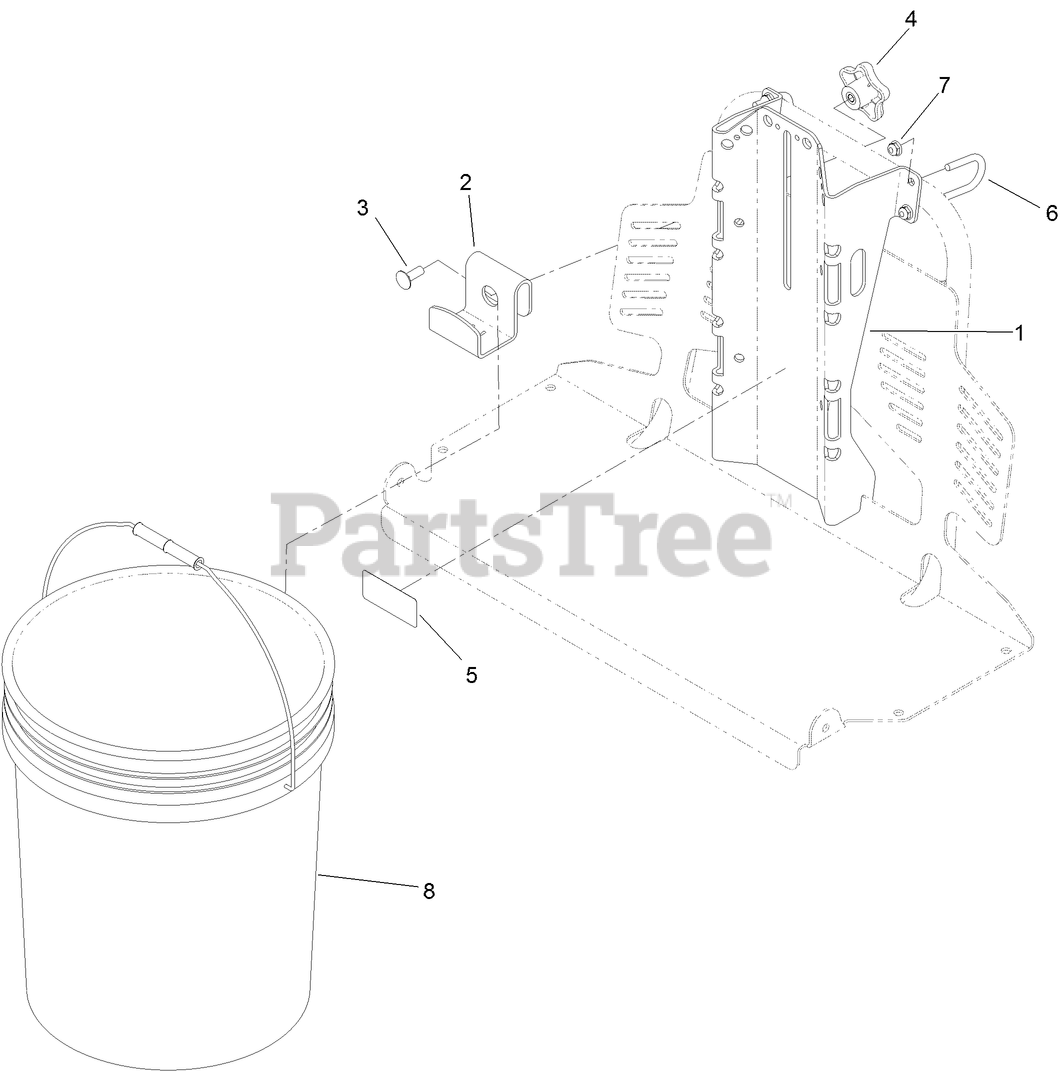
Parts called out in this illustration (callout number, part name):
1	BRACKET-MOUNT, UNIVERSAL
2	BRACKET-TOP
3	BOLT-CARR
4	KNOB-HANDLE
5	DECAL-WEIGHT, MAXIMUM
6	U-BOLT
7	NUT-HF
8	BUCKET-5 GALLON
